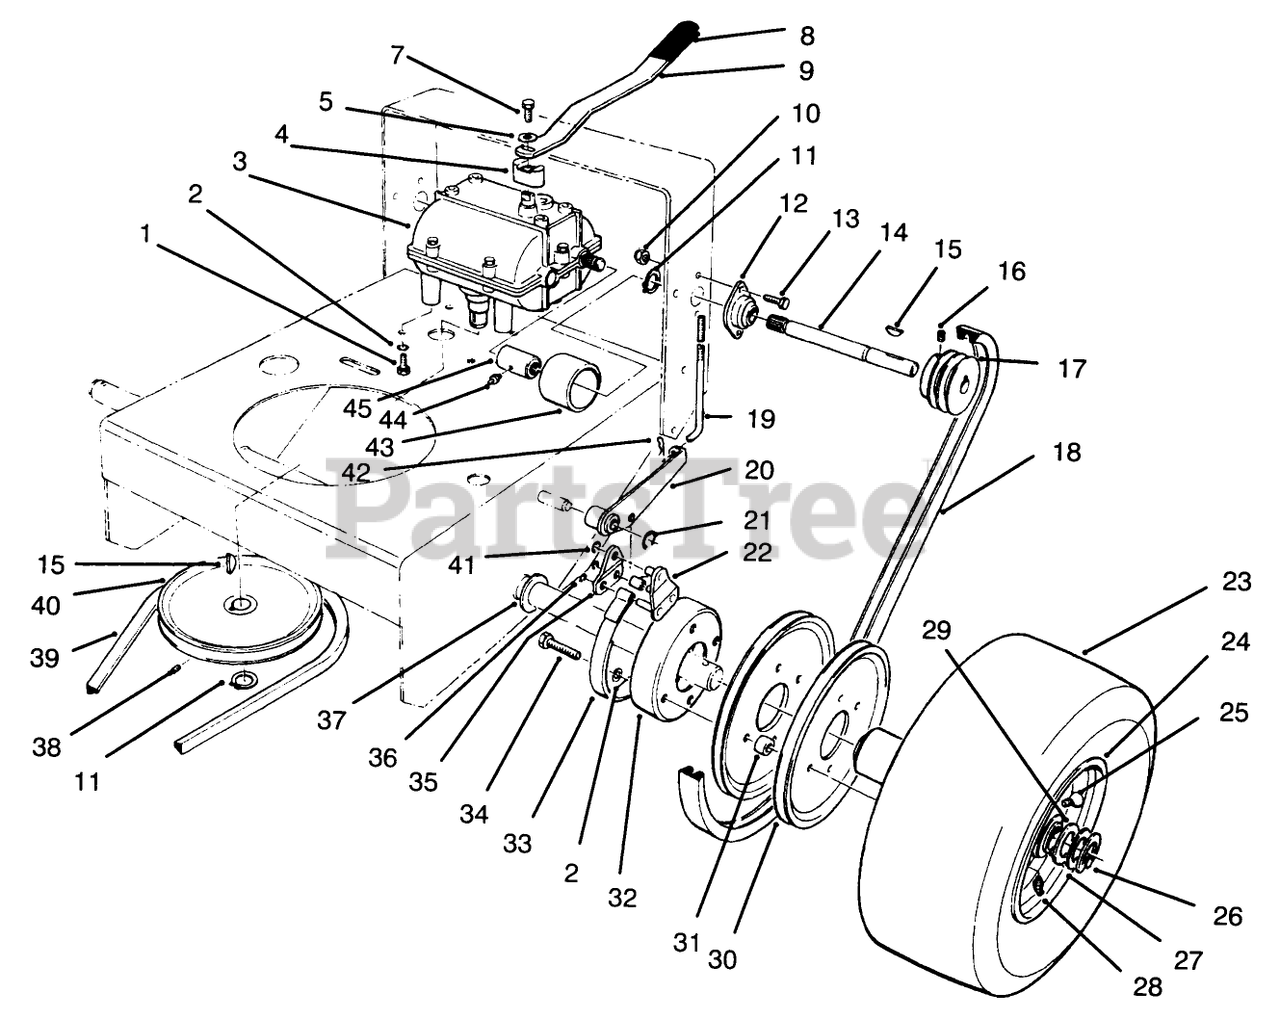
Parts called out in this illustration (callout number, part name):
1	SCREW-HH
2	WASHER-LOCK
3	TRANSMISSION
4	MOUNT-LEVER, SHIFT
5	SPACER
7	SCREW-HH
9	Lever-Shift
10	NUT-LOCK, NI
11	RING-SNAP, EXTERNAL
12	BEARING-EXTERNAL SHAFT
13	SCREW-HH
14	SHAFT-EXTENSION, RH
15	KEY-WOODRUFF
16	SCREW-SET, HS
17	Pulley-Drive
18	V-BELT
19	ROD-BRAKE
20	Arm-Brake LH
21	RING-RETAINING
22	LINK-Brake
23	TIRE-FRONT
24	WHEEL ASM
25	STEM-VALVE
26	RING-RETAINING
27	BEARING-BALL
28	FITTING-GREASE
29	WASHER-THRUST
30	Pulley-Wheel
31	SPACER-PULLEY
32	Drum-Brake
33	BAND-BRAKE
34	SCREW-HH
35	Plate-Link
36	RING-RETAINING
37	WASHER-WHEEL
38	SCREW-SET, HSH
39	BELT V
40	PULLEY-DRIVEN
41	RING-RETAINING, EXTERNAL
42	PIN-COTTER
43	GUARD-COUPLER
44	FITTING-GREASE
45	COUPLER
